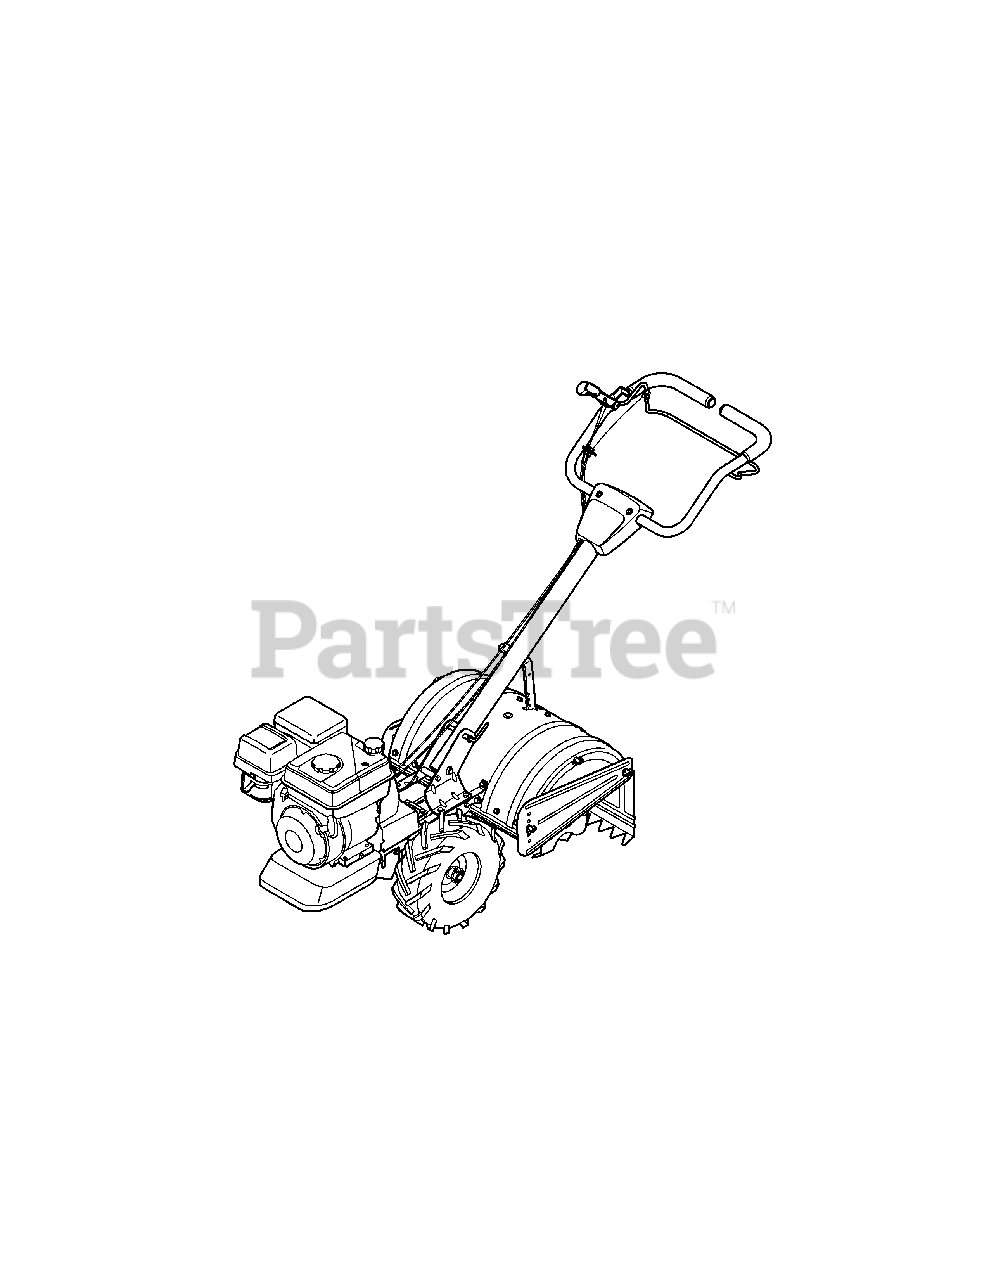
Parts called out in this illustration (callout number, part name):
NA	Pre Filter
NA	Tines-Inner (LH)
NA	Tines-Inner (RH)
NA	Rim
NA	Tire
NA	Handle Knob
